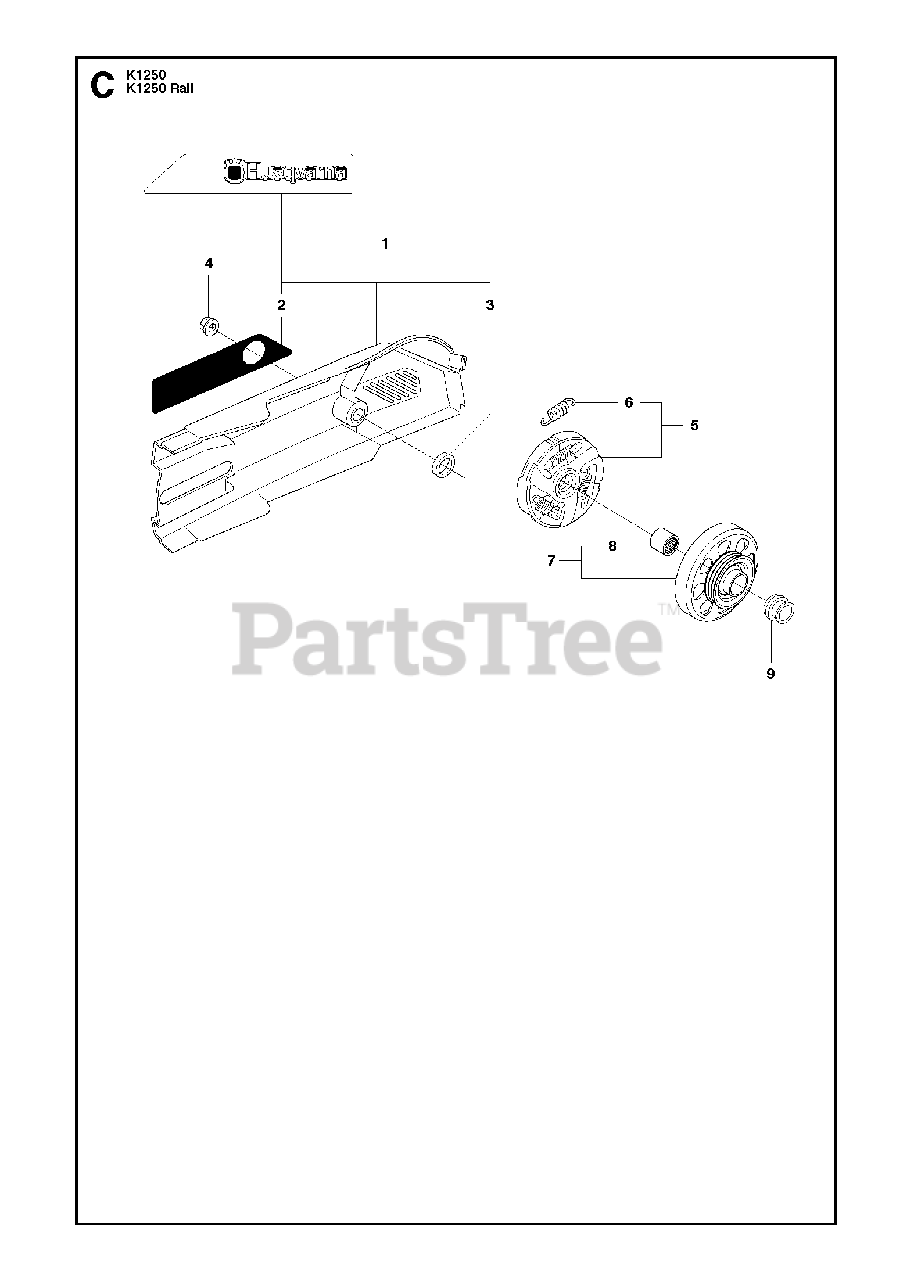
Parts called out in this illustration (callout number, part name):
1	BELT GUARDIncl. 2, 3
3	SPACING SLEEVE
5	CLUTCH ASSYIncl. 6
6	CLUTCH SPRING
7	DRIVE SPROCKET"14"". Incl. 8"
7	DRIVE SPROCKET"16"". Incl. 8"
8	NEEDLE BEARING
9	SPACING SLEEVE
